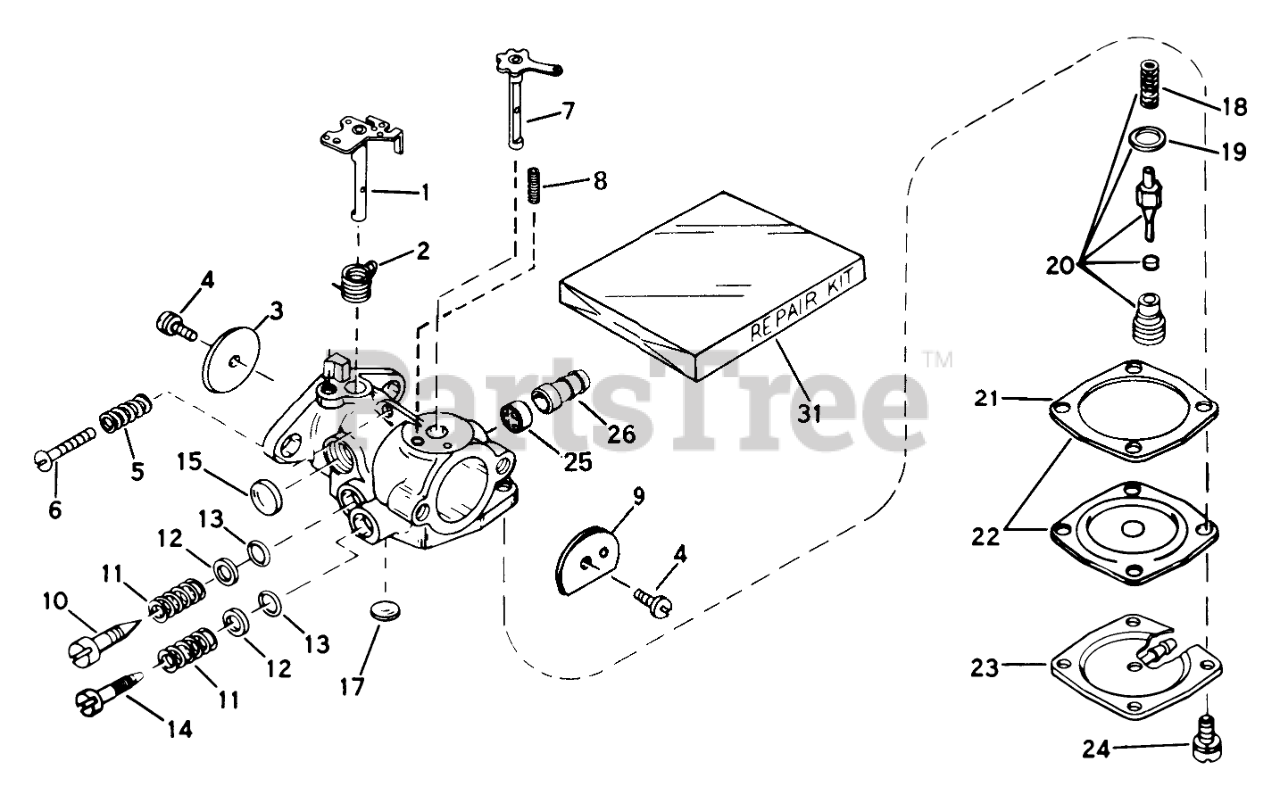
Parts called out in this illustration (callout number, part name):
1	Shaft & Lever Assy., Throttle
2	Spring Return
3	Shutter-Throttle
4	Screw-Shutter
5	Spring-Tension
6	Screw-Throttle Crack Screw / Idle Speed
7	Shaft & Lever Assembly
8	Spring-Positioning, Choke
9	Shutter-Choke
10	Screw-Idle Adjustment
13	"O"Ring
14	Screw Main Adjustment
15	Plug-Welch, Idle Mixture Well
17	Plug Welch
18	Spring-Valve
19	Gasket-Valve Seat
20	Inlet Needle, Seat, Spring & Gasket Assembly (Incl.Nos. 18 & 19)
21	Gasket-Diaphragm
22	Diaphragm Assembly (Incl. No. 21)
23	Cover, Diaphragm
24	Screw, Diaphragm Cover
25	Valve Check
26	Fuel Fitting
31	Kit-Repair
